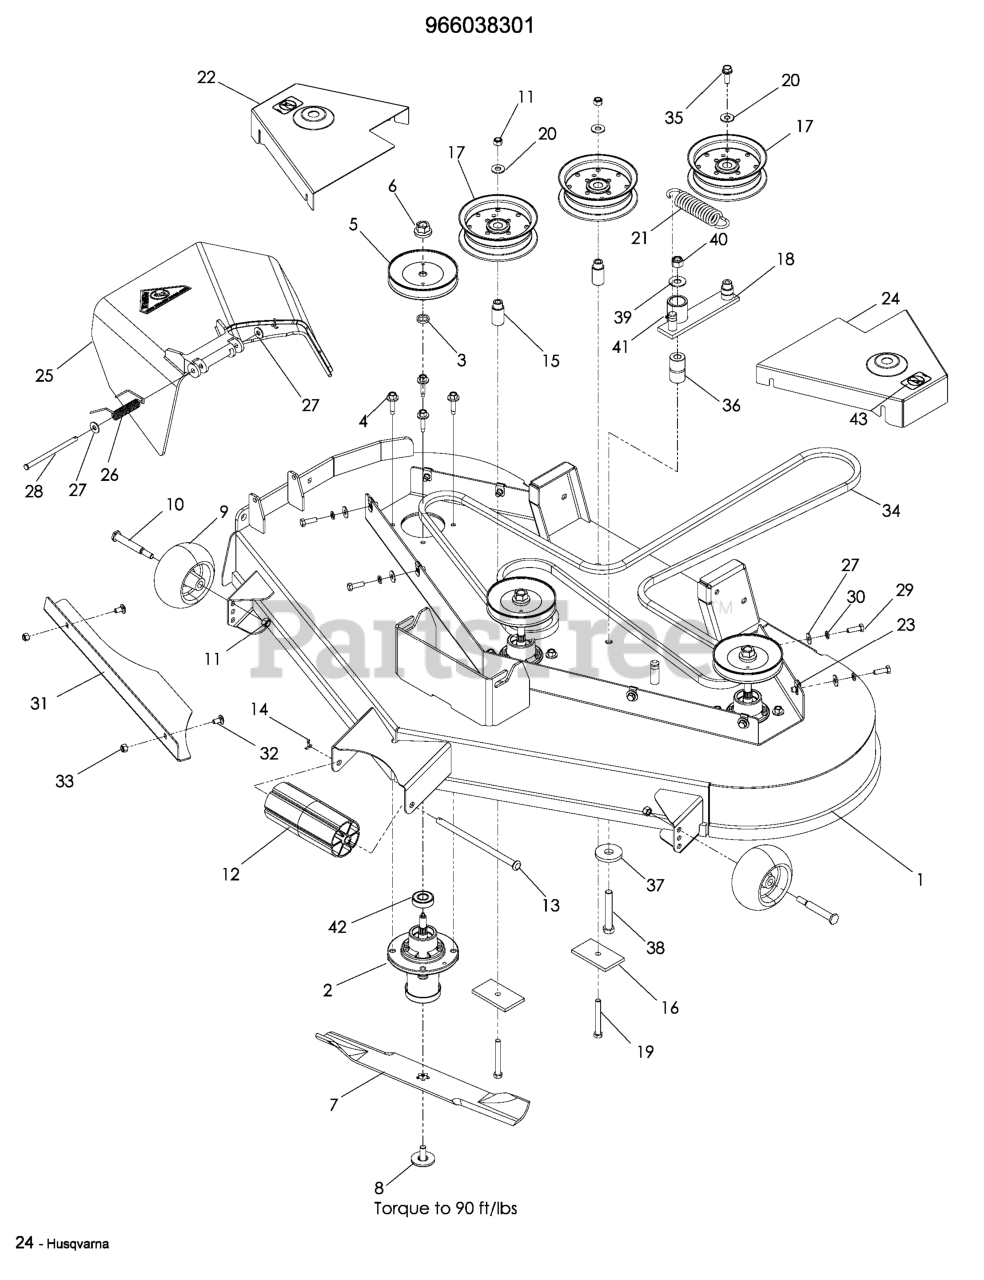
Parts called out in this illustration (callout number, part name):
1	DECK.SVC.W/DECALS.EZ52
2	MANDREL.DECK.ASSEMBLY
3	WASHER-SPACER
4	WASHER HEAD SCREW
5	PULLEY
6	LOCKNUT - 9/16
7	BLADE, 18"
8	BLADE BOLT ASSY-7/16" TB REPL
9	GAUGE WHEEL
10	SHOULDER BOLT 1/2X2-5/8 ZD SPE
11	NUT 3/8-16 NYLOC
12	NOSE ROLLER 48"
13	NOSE ROLLER ROD
14	RP_COTTER PIN 1/8 X 3/4
15	IDLER BUSHING
16	SUPPORT PLATE
17	PULLEY, IDLER
18	PULLEY - IDLER, NYLON
19	HCS 3/8C X 3
20	WASHER 3/8 FLAT
22	BELT SHIELD, RIGHT 52, ORG
23	U-CLIP 5/16-18 NUT RETAINER
24	BELT SHIELD, LEFT 52, ORG
25	DISCHARGE CHUTE 52"
26	SPRING - TORSION
27	WASHER 5/16 FLAT
28	PIN-CLEVIS 5/16 DIA X 5.19 ZD
29	HCS 5/16C X 1
30	WASHER.LOCK.HVY.HLCL.SPR.5/16
31	CONFINEMENT PLATE, 52"
32	CARRIAGE BOLT 5/16C X 5/8"
33	NUT 5/16 NYLOC
34	BELT, DECK
35	4CS 3/8C X 1 SERRATED HEAD
36	PIVOT BUSHING
37	WASHER, SUPPORT
38	HCS 1/2C X 3 1/4
39	WASHER 1/2 FLAT
40	NUT 1/2-13 HEX NYLOC ZD
41	ZERK
42	BEARING, BALL
43	DECAL, NO STEP
